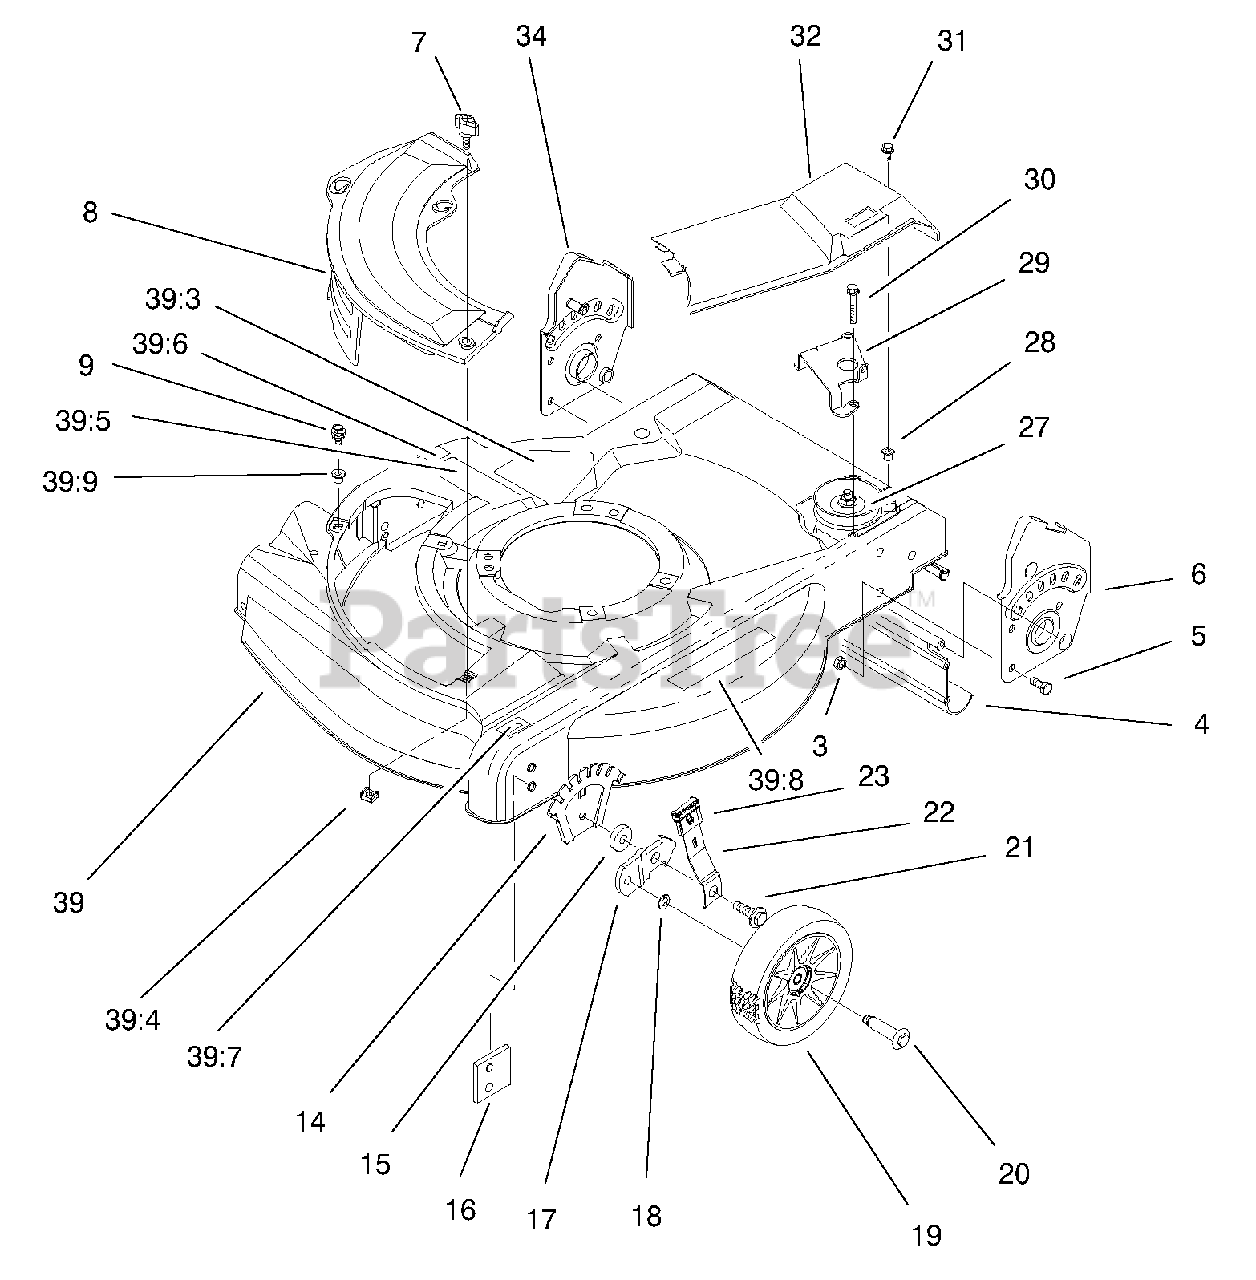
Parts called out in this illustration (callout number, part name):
3	Nut-Lock NI
4	Shield-Trailing
5	Screw-HH
6	LH Handle Brkt ASM
8	Plate-Mulch
9	Screw-Sems
14	Plate-Hght Adj
15	Washer-Wheel
16	Plate-Baffle
17	Bracket-Wheel Ht Adj
18	Washer-Wheel Bolt
19	6" Wheel & Tire ASM
20	Bolt-Shoulder 6" Wheel
21	Bolt-Shoulder
22	Arm-Front Spring
23	Knob-Height Adj Lever
27	Assembly-Gear Case
28	Grommet
29	Guide-Transmission
30	Screw-Thread Forming
31	Screw-Pth
32	Cover-Drive
34	RH Handle Brkt ASM
39	ASM-Housing/Baffle Sp
39:3	Decal-Danger
39:4	Nut-Cage
39:5	Decal-Warning
39:6	Decal-HOC R
39:7	Decal-HOC L
39:8	Decal-Instruction
39:9	Grommet-Plastic
